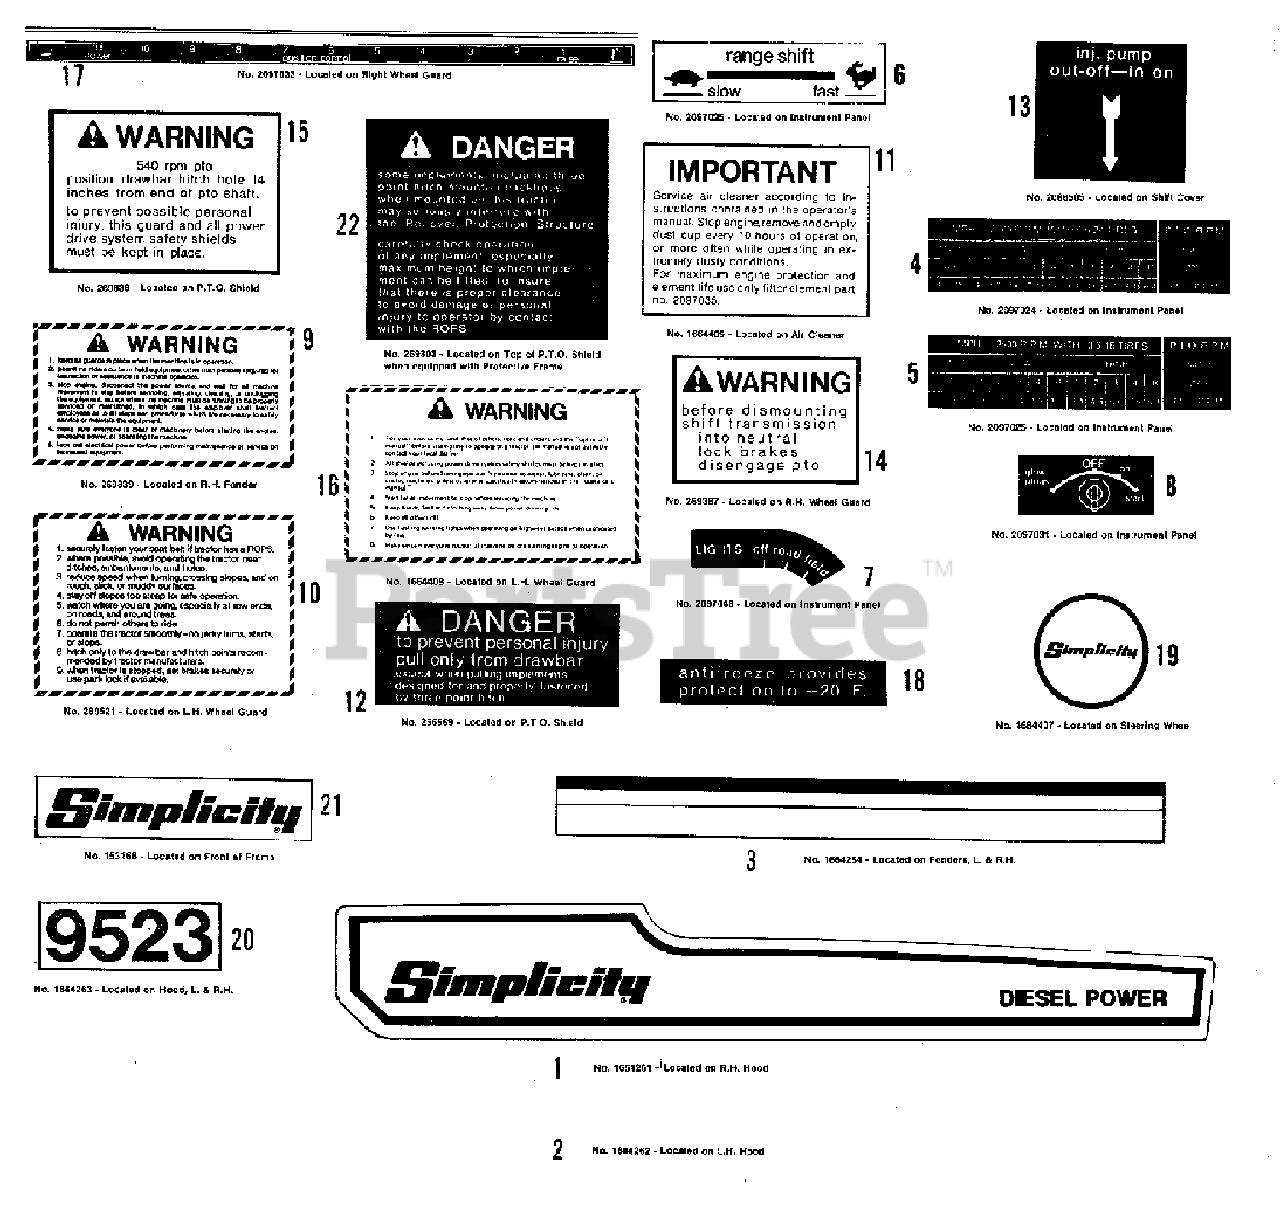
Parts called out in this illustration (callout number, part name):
1	DECAL, hood, R.H.
2	DECAL, hood, L.H.
3	DECAL, stripe
4	DECAL, speed (w/9.5-24 Tires)
5	DECAL, speed (turf)
6	DECAL, range shift
7	DECAL, lights
8	DECAL, starter switch
9	DECAL, warning
10	DECAL, warning
11	DECAL, air cleaner
12	DECAL, danger (P.T.O. shield)
13	DECAL, injection pump
14	DECAL, dismounting instr.
15	DECAL, warning (P.T.O. shield)
16	DECAL, warning
17	DECAL, (Pos. Control)
18	DECAL, antifreeze
19	DECAL, trademark, steering wheel
20	DECAL, 9523
21	DECAL, Simplicity
22	DECAL, danger (P.T.O. shield)
